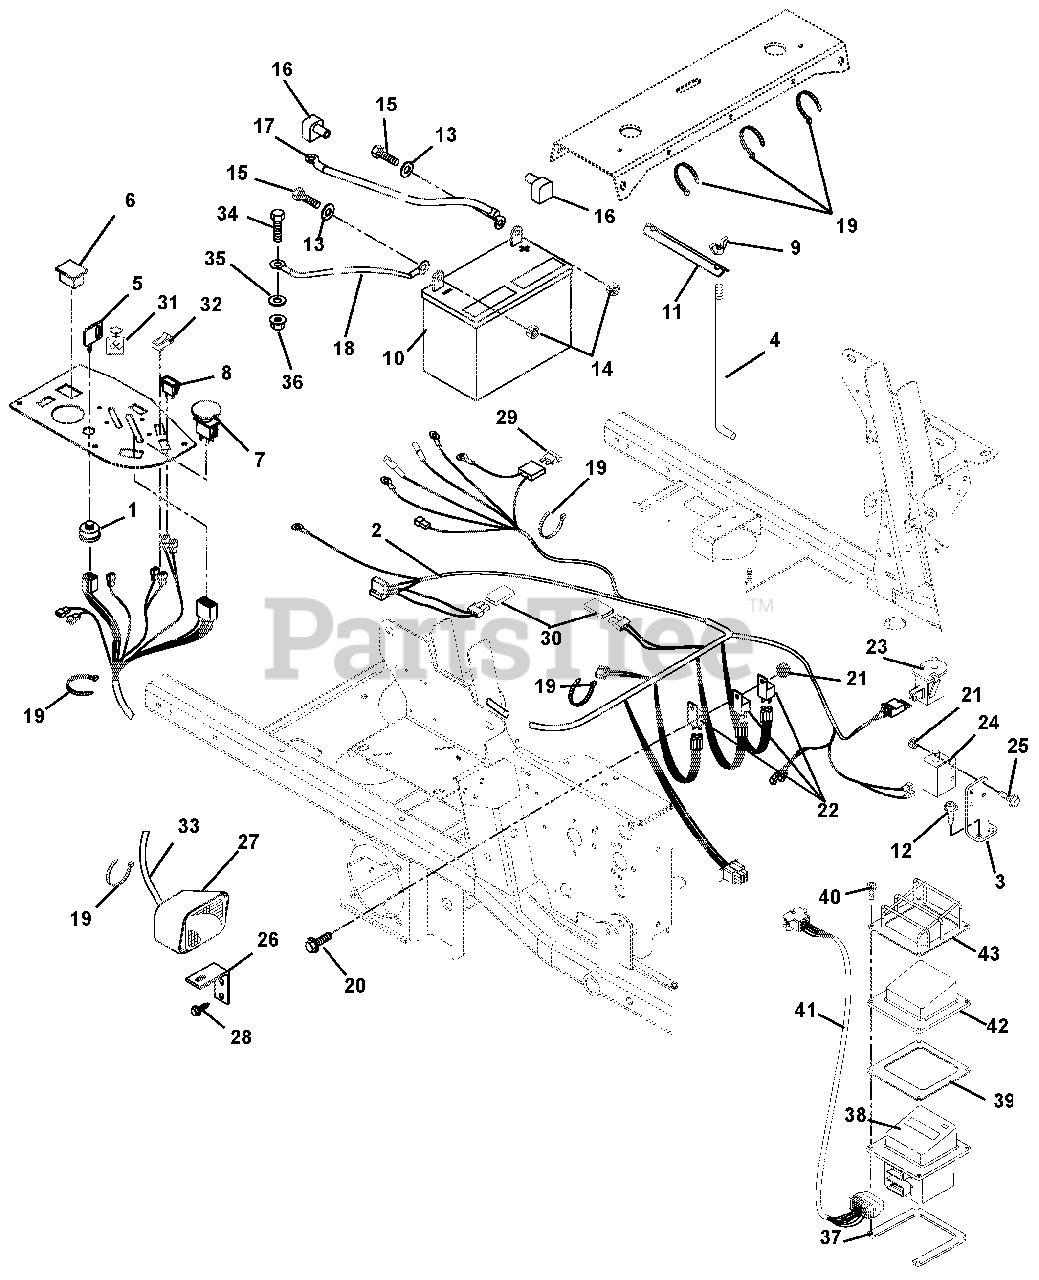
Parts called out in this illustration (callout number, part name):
1	Switch, Ignition
2	Harness, Z-6 Pin Wiring (EYE-Q) (066, 067, 068, 070, 071, 072)
3	Mount, Safety Switch
4	Rod, Battery Holddown .25 x 6.62
5	Key, with Shield
7	Switch, PTO Clutch
8	Light-Indicator Kit (066, 067, 068, 070, 071, 072)
9	Nut-Locking Wing .25-20
11	Hold Down
12	Screw-Tapping .25-20 x .50 Hex Washer Head
13	Washer-Flat-Steel .281 x .620 x .065
14	Nut-Locking-Top-Flange .25-20
15	Bolt-Hex .25-20 x .75 Grade 5
16	Battery Terminal Boot, Red
17	Starter Cable 13 in.
18	Ground Cable
19	Cable Tie
20	Screw-Machine 10-24 x .50 Hex Washer Head
21	Nut-Locking-Nylon 10-24 With Insert
22	Relay (Included with Harness)
23	Switch- Snap Mounting
24	Switch-Single Pole
25	Screw-Machine 10-24 x .75 Hex Washer Head
26	Bracket, Headlight Mounting Left
27	Headlight
28	Screw-Tapping .38-16 x .50 Hex Washer Head
29	Fuse, 30 Amp (Included with Harness)
30	Diode, Connector Shell
31	Key Chain
32	Switch, Light
33	Harness, Headlight Kit
34	Bolt-Hex .31-18 x .75 Grade 5
35	Washer-Flat-Steel .344 x .688 x .065
36	Nut-Locking-Top-Flange .31-18
37	Spacer, Enclosure Mounting (Bottom)
38	Assembly, Eye-Q
39	Gasket, Eye-Q
40	Screw, Machine 10-24 x 1.00
41	Harness, Eye-Q
42	Guard, Element
43	Guard, Vinyl Eye-Q
